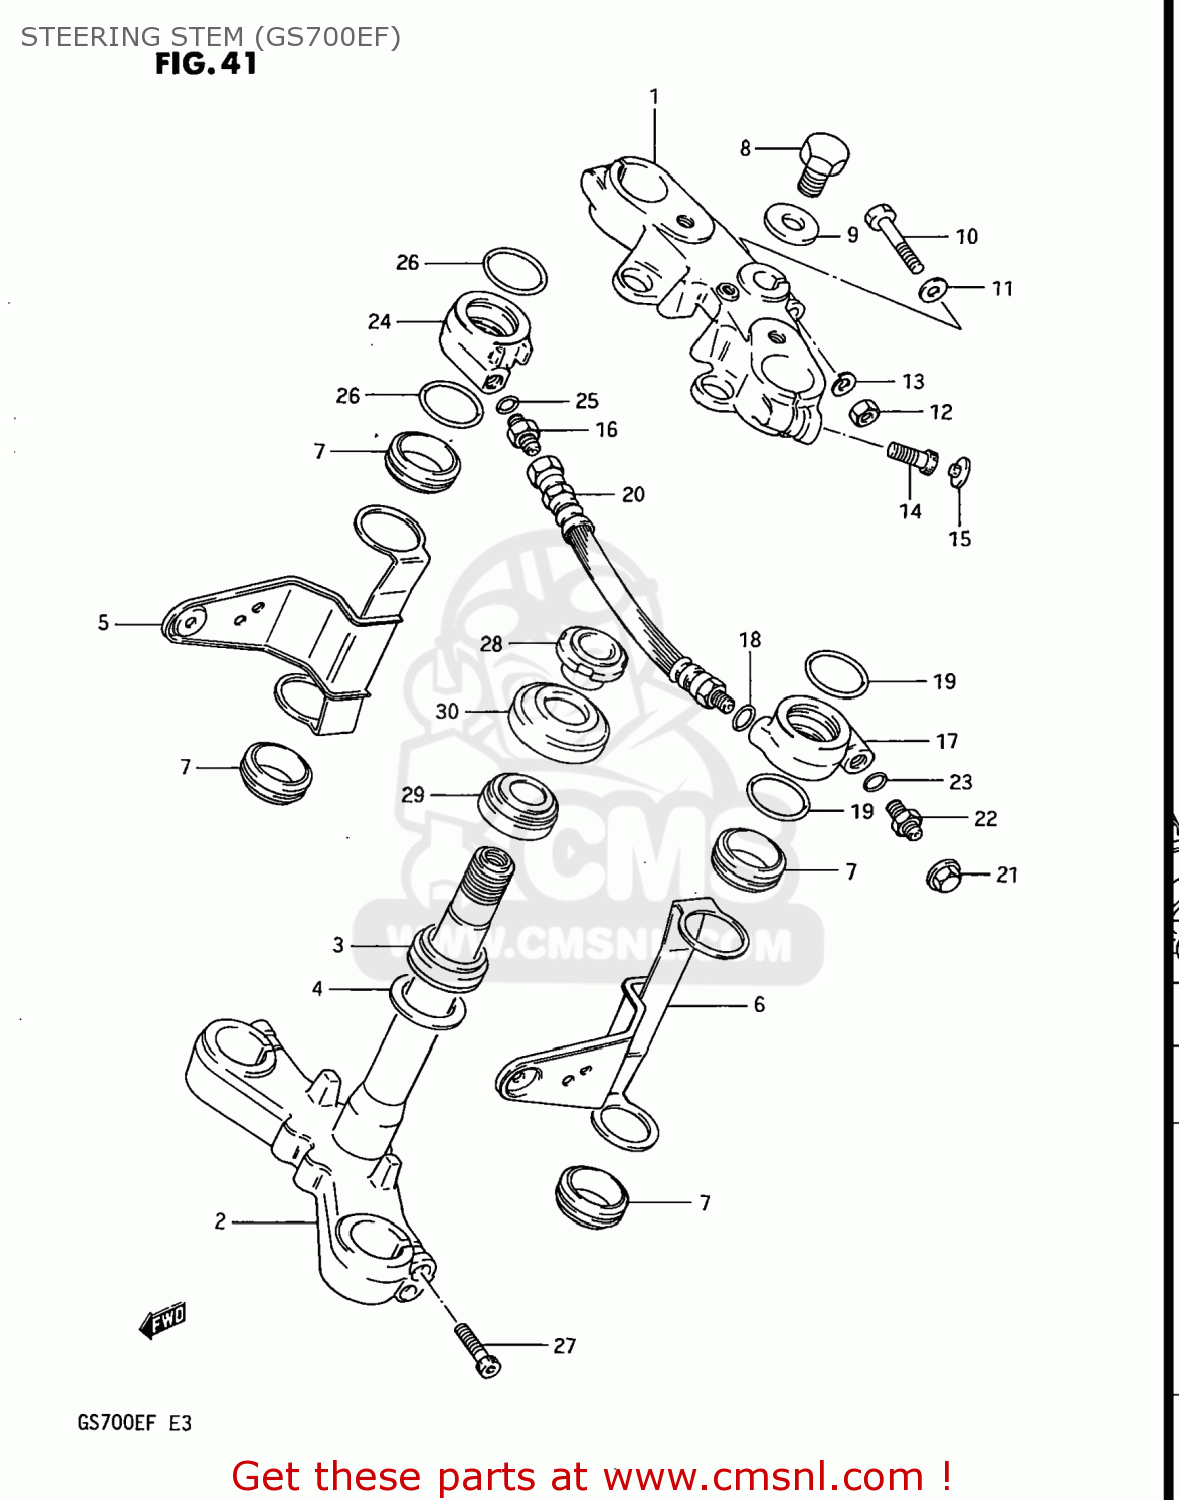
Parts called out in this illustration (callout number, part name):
1	HEAD,STEERING STEM
2	STEM,STEERING
3	BEARING
4	WASHER,THRUST
5	BRACKET,HEADLAMP HOUSING
6	BRACKET,HEADLAMP,LEFT
7	CUSHION,HEADLAMP BRACKET
8	BOLT
9	WASHER,STEM HEAD
10	BOLT
11	WASHER
12	NUT 8MM
13	WASHER,LOCK,8.
14	NUT,STEM HEAD
15	CAP(OD:20)
16	CONNECTOR
17	JOINT,AIR,LEFT
18	O-RING (D:3.8 ID:19)
19	O RING
20	TUBE,JOINT
21	CAP,FRONT FORK AIR VALVE
22	VALVE,AIR
23	O-RING (D:3.8 ID:19)
24	JOINT,AIR,RIGHT
25	O-RING (D:3.8 ID:19)
26	O RING
27	BOLT 8X35
28	NUT,STEERING STEM
29	TAPER,ROLLER BEARING
30	DUST SEAL,STEERING UPR
